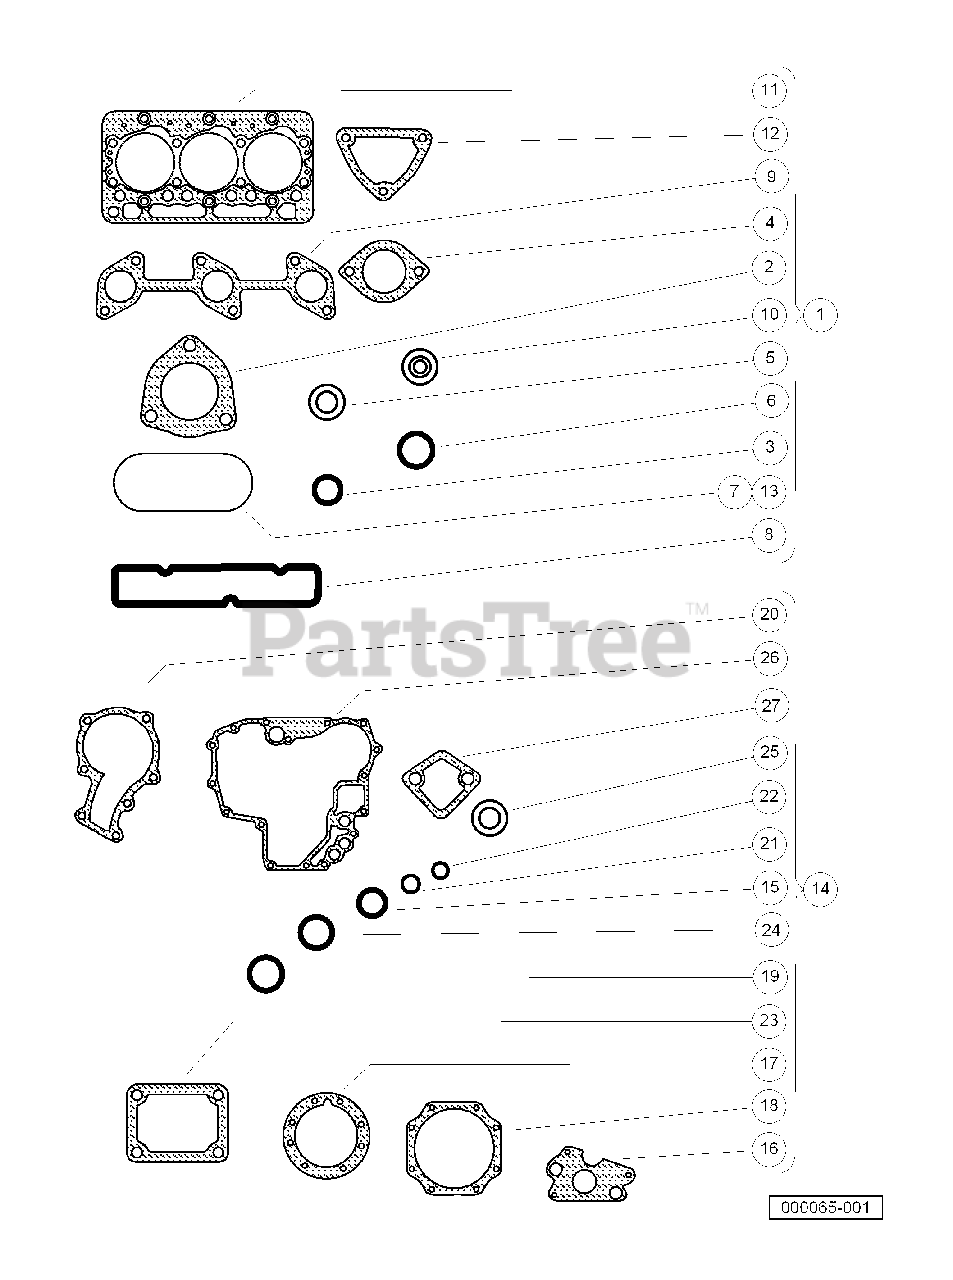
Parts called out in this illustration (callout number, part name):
1	Kit, Gasket Upper, D722
2	Gasket, Exhaust Diesel
3	O Ring, 8 X 7
4	Gasket, Thermostat
5	Gasket, 6 X 10
6	O Ring, 30 X 36
7	Gasket, Head Cover
8	Gasket, Intake Manifold
9	Gasket, Ex-manifold
10	Seal, Valve Stem
11	Gasket, Cylinder Head
12	Gasket, Water Flange
13	Gasket, Cylinder Head Cover
14	Kit, Gasket Lower, D722
15	O Ring, 18 X 13
16	Gasket, Oil Pump
17	Gasket, Bearing Case
18	Gasket, Cover
19	O Ring, 23 X 26
20	Gasket, Water Pump, D722
21	O Ring, 19 X 16
22	O Ring, 9 X 7
23	Gasket, Control Plate
24	O Ring, 20 X 17
25	Gasket, Idle Apparatus, Rear
26	Gasket, Gearcase, D722
27	Gasket, Fuel Pump, D722
